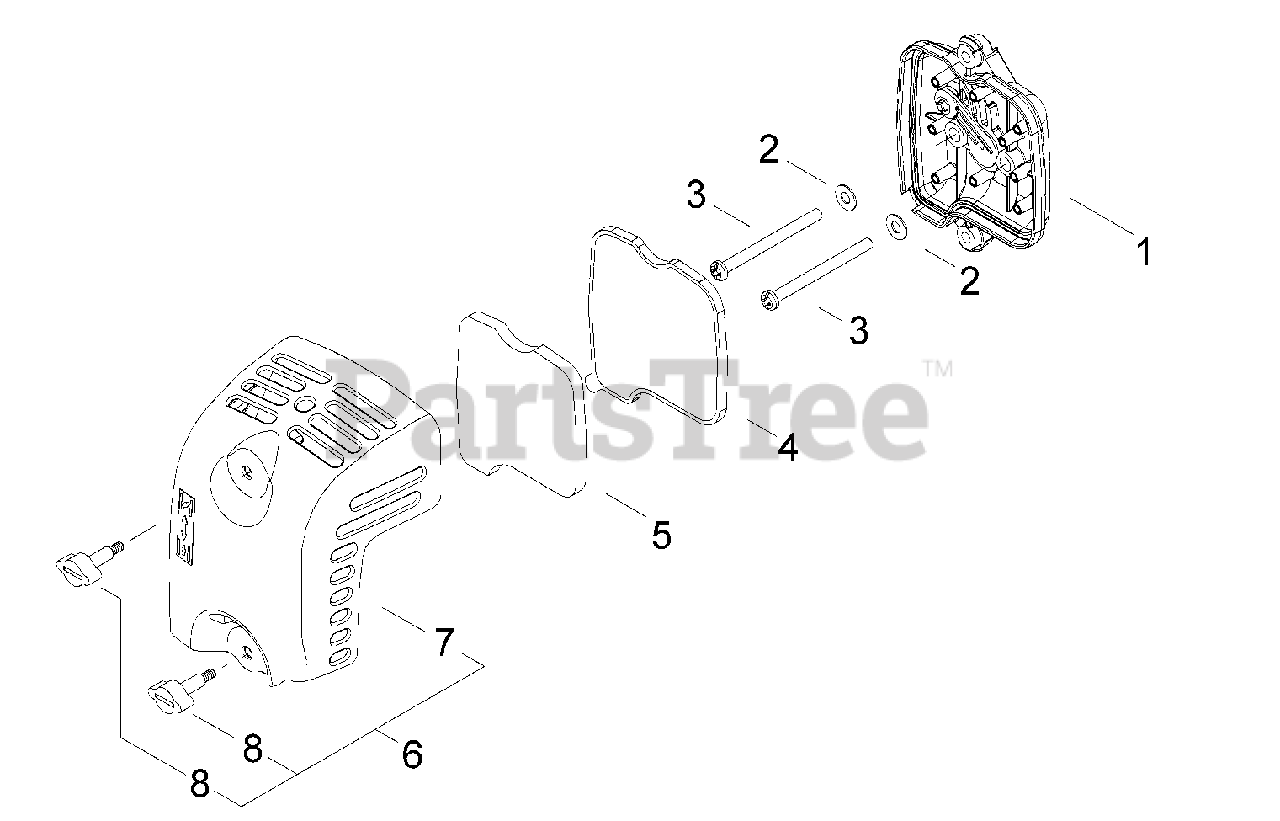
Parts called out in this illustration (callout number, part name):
1	CASE ASSY, AIR FILTER
2	WASHER 5 MM
3	SCREW M5×60
4	FILTER, AIR
5	PRE-FILTER, FOAM
6	COVER ASSY, AIR FILTER
7	COVER, AIR FILTER
8	THUMBSCREW M5
